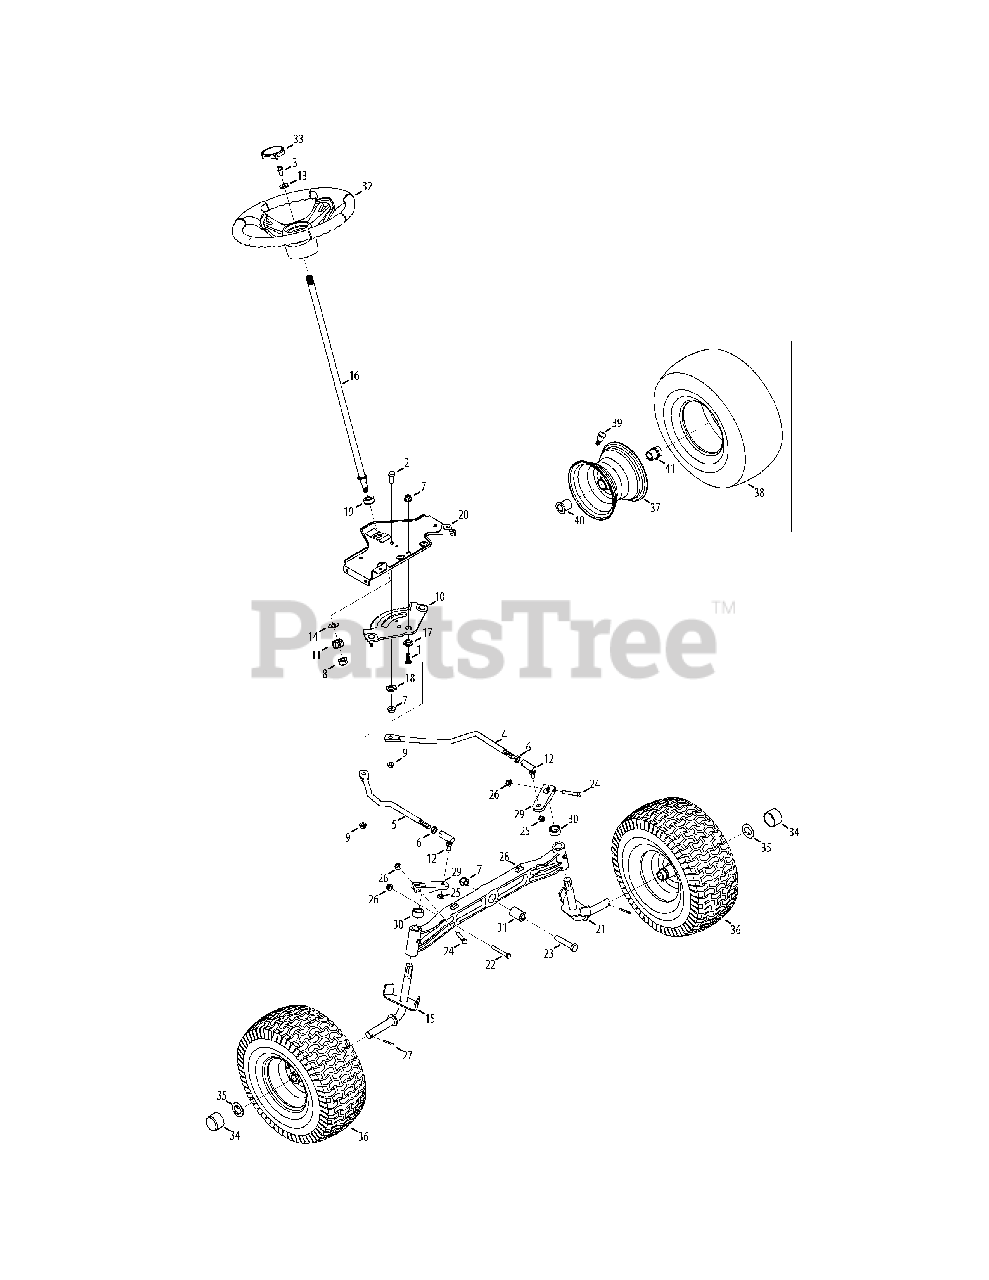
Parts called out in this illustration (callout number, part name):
1	Hex Head Screw, 3/8-16:1.00
2	Hex Head Screw, 3/8-16:1.00
3	Hex Head Screw, 5/16-18:1.00
4	LH Drag Link
5	RH Drag Link
6	Jam Nut, 7/16-20
7	Flangelock Nut, 3/8-16
8	Flangelock Nut, 7/16-20
9	Flangelock Nut, 5/16-18
10	Steering Gear
11	Steering Pinion Gear
12	Ball Joint, 7/16-20
13	Flat Washer, .406 x .875 x .105
14	Flat Washer, .51 x 1.12 x .06:HT
15	RH Axle Assembly
16	Steering Shaft, .625 OD x 24.25 LG
17	Shoulder Spacer, .385X 1.25 x .3025
18	Spacer, .38 x 1.375
19	Hex Flange Bearing 5/8 PM
20	Steering Support Bracket
20	Screw, .750 5/16-18
21	LH Axle Assembly
22	Hex Head Screw, 5/16-18:2.25
23	Hex Head Screw, 3/8-16:2.50
24	Hex Head Screw, 5/16-18:1.75
25	Hexlock Nut, 3/8-24
26	Flangelock Nut, 5/16-18
27	Cotter Pin, 5/32:1.25
28	Pivot Bar Axle
29	Steering Block
30	Spacer, .71 ID x .125 OD x .56LG
31	Spacer, .385 x 1.00 x 1.5075
32	Steering Wheel, 5 Style
33	Steering Wheel Cap, 5 Style
34	Bumper Cap
35	Flat Washer, .781ID x 1.590OD
36	Wheel Assembly, 5 Style
37	Rim Assembly, 5 Style
38	Tire, 5 Style
39	Tubeless Air Valve
40	Flange Bearing, .760 x 1.00 x 1.20LG
41	Flange Bearing, .760ID
